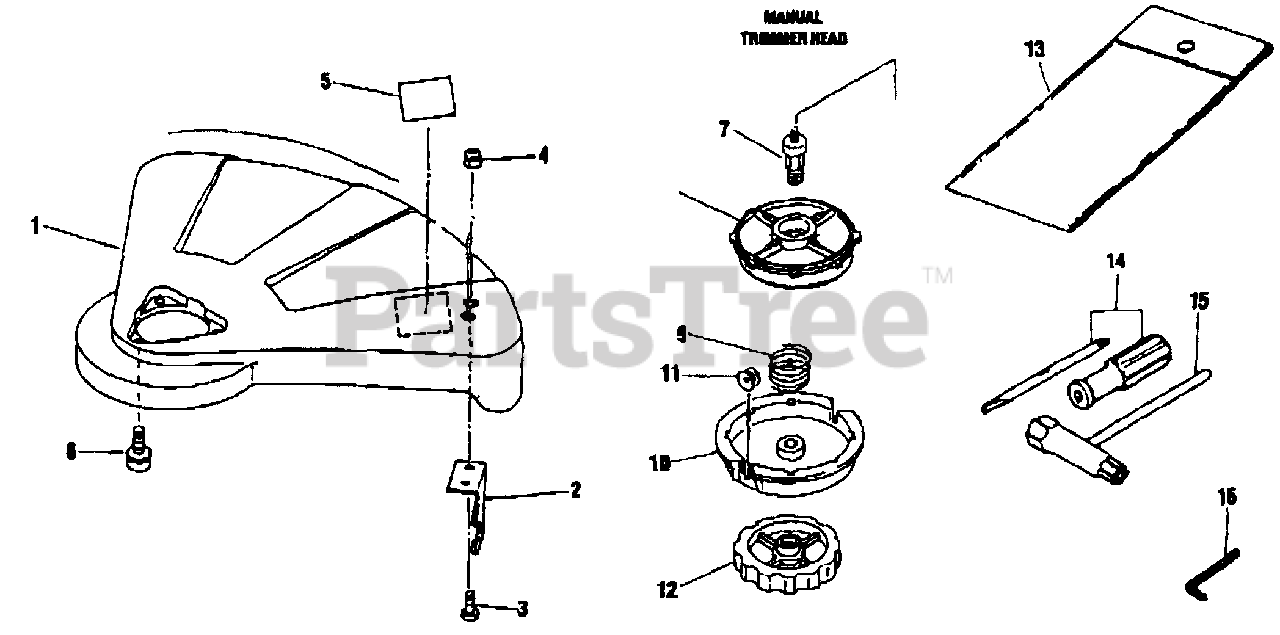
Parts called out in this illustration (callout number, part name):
1	GUARD
2	KNIFE, TRIMMER LINE
4	NUT - NYLON
5	LABEL, CAUTION
6	SCREW
7	SHAFT BOLT
8	SPOOL, INNER
9	SPRING
10	SPOOL HOUSING
12	KNOB LH
13	BAG, TOOL
14	SCREWDRIVER
15	T-WRENCH 13×19 MM
16	WRENCH - 4
